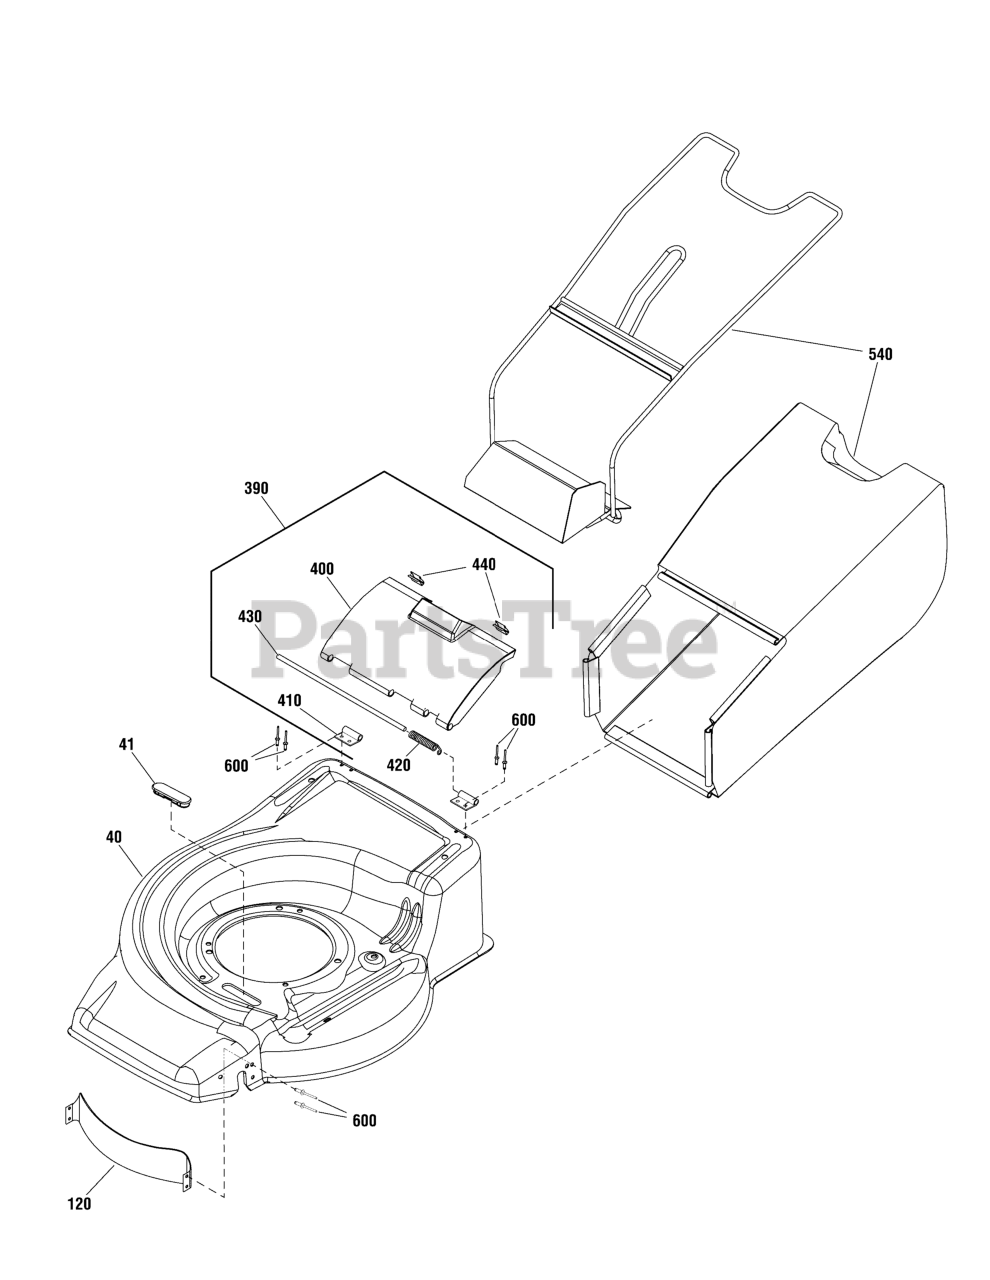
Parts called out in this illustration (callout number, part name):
40	* BASEPLATE, Flame Red
40	BASEPLATE, Brunswick Green
41	PLUG, Muffler Slot
120	FRONT SKIRT
390	REAR FLAP ASSEMBLY
400	FLAP, Rear
410	BRACKET, Flap
420	SPRING, Flap
430	PIVOT ROD
540	CATCHER ASSEMBLY
600	RIVET
